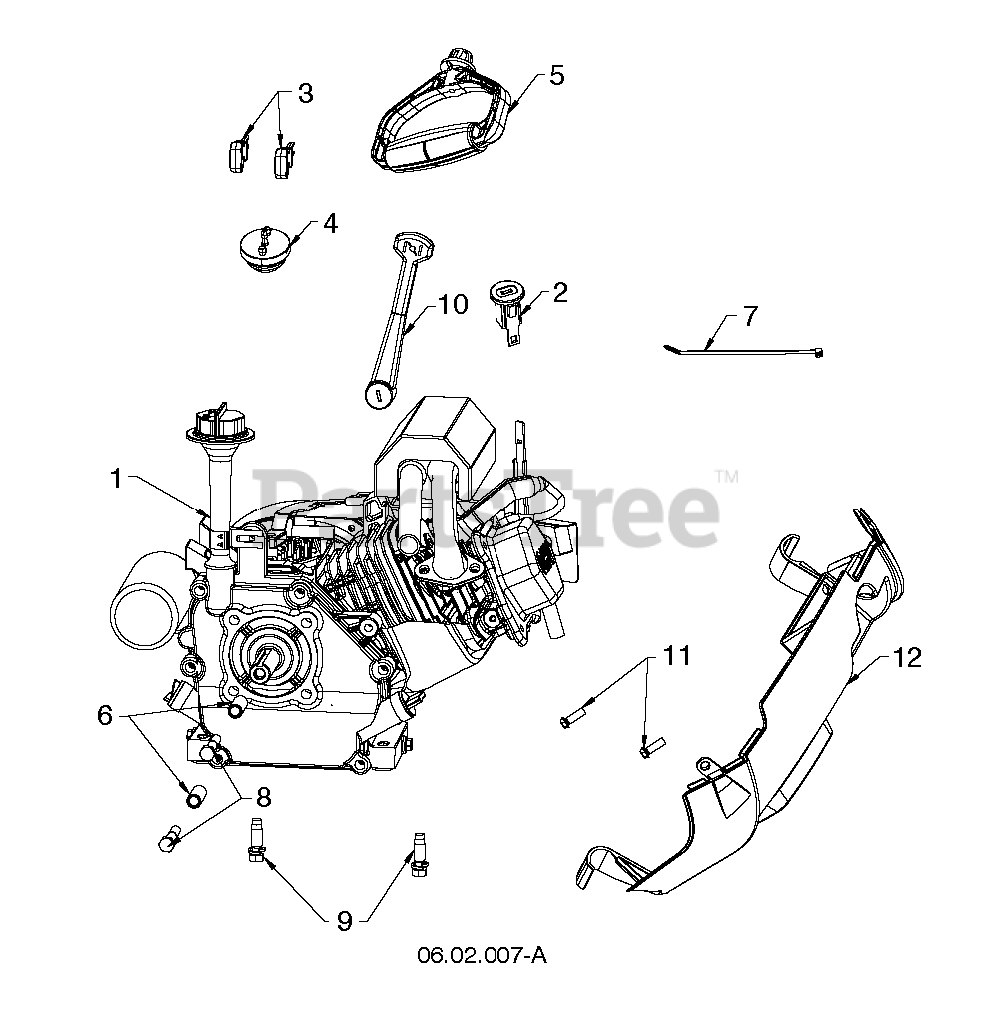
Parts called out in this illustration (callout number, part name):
2	KEY HOUSING
3	RP BULB.PRIMER
4	RP BULB.PRIMER
5	HANDLE.STARTER.SNOW
6	SPACER.ENGINE
7	WIRE.TIE
8	SCREW. 5/16-24 X 2.00"HHCS
9	BOLT 3/8-16X1-1/8
10	LEVER.CHOKE
11	SCREW.HX.13X.750
12	COVER.REAR.LOWER.SSST.HUSQ.GRE
